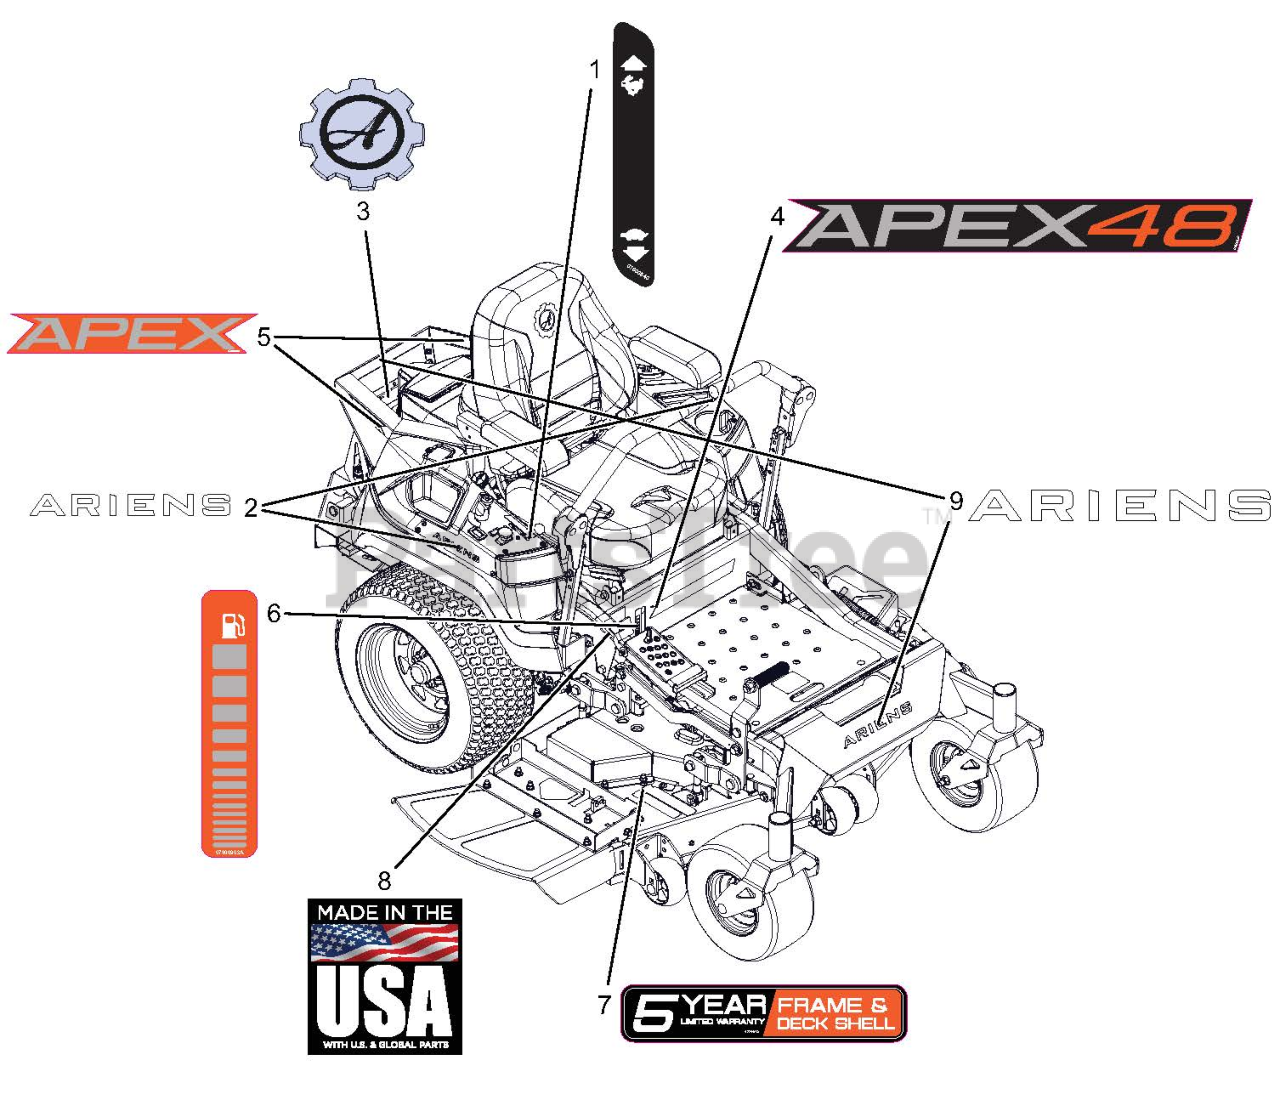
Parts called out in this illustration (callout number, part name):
1	DECAL, DASH DECAL
2	DECAL, ARIENS (6.50")
3	DECAL, ARIENS-GEAR BADGE -THK
4	DECAL, 48" APEX KICKPLATE
5	DECAL, APEX FENDER
6	DECAL, ARIENS FUEL LEVEL
7	DECAL, DECK 5 YEAR-ARIENS
8	DECAL, MADE IN USA
9	DECAL - ARIENS 9.625"
